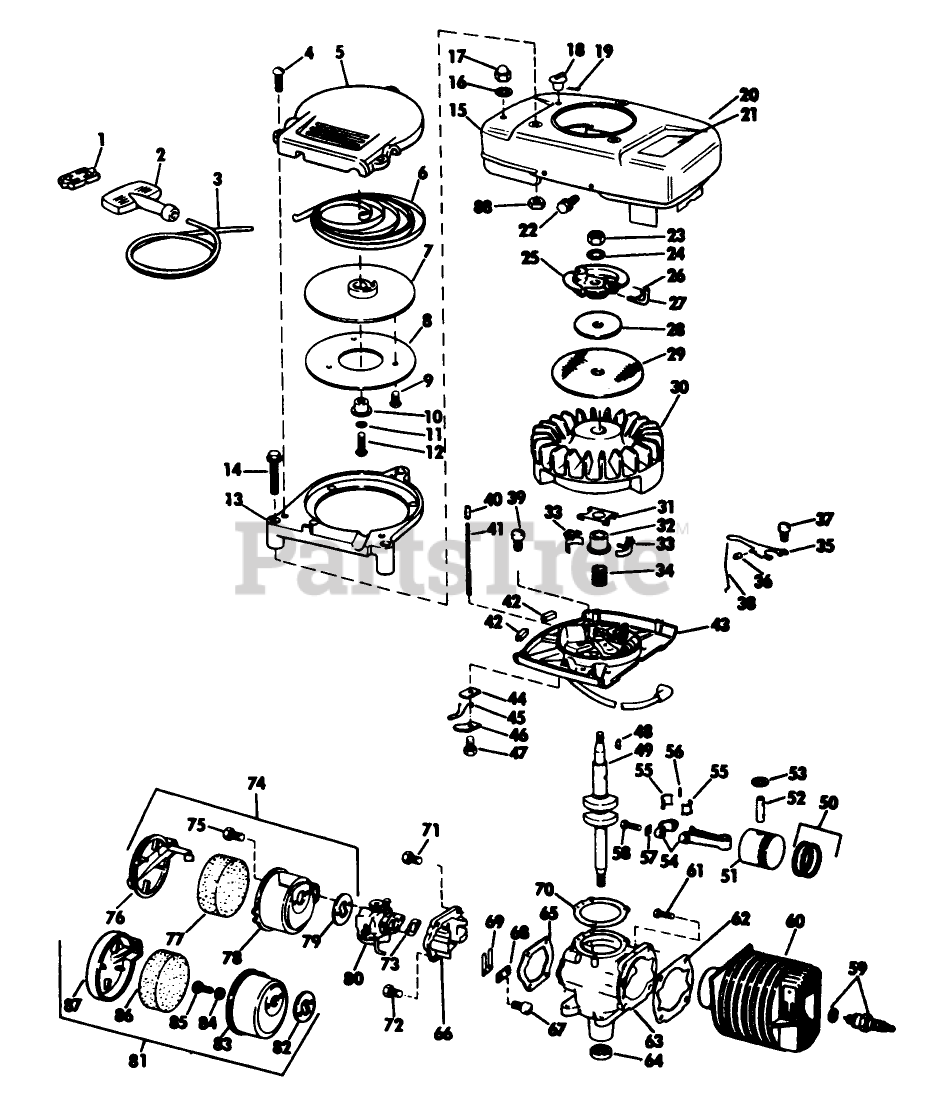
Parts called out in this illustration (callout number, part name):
6	RECOIL SPRING
17	PALNUT S
18	KNOB, CHOKE BAR
19	Cotter Pin-Choke Knob
21	Decal-Instruction
22	SCREW S
26	Spring-Starter Pin
27	PIN - STARTER
32	COLLAR S
35	GOVERNER LEVER AY
36	WEAR BLOCK S
38	GOVERNOR ROD S
47	Screw Shut-off Switch
53	RING-RETAINING
55	LINER ASM
62	GASKET S
68	PLATE-BACKUP, REED
70	GASKET S
71	SCREW S
72	SCREW S
73	GASKET S
75	SCREW S
77	AIR FIL.ELEM S
79	GASKET S
82	GASKET S
83	FILTER CHAMBER S
85	SCREW S
86	AIR FIL.ELEM S
87	CHAMBER AY S
